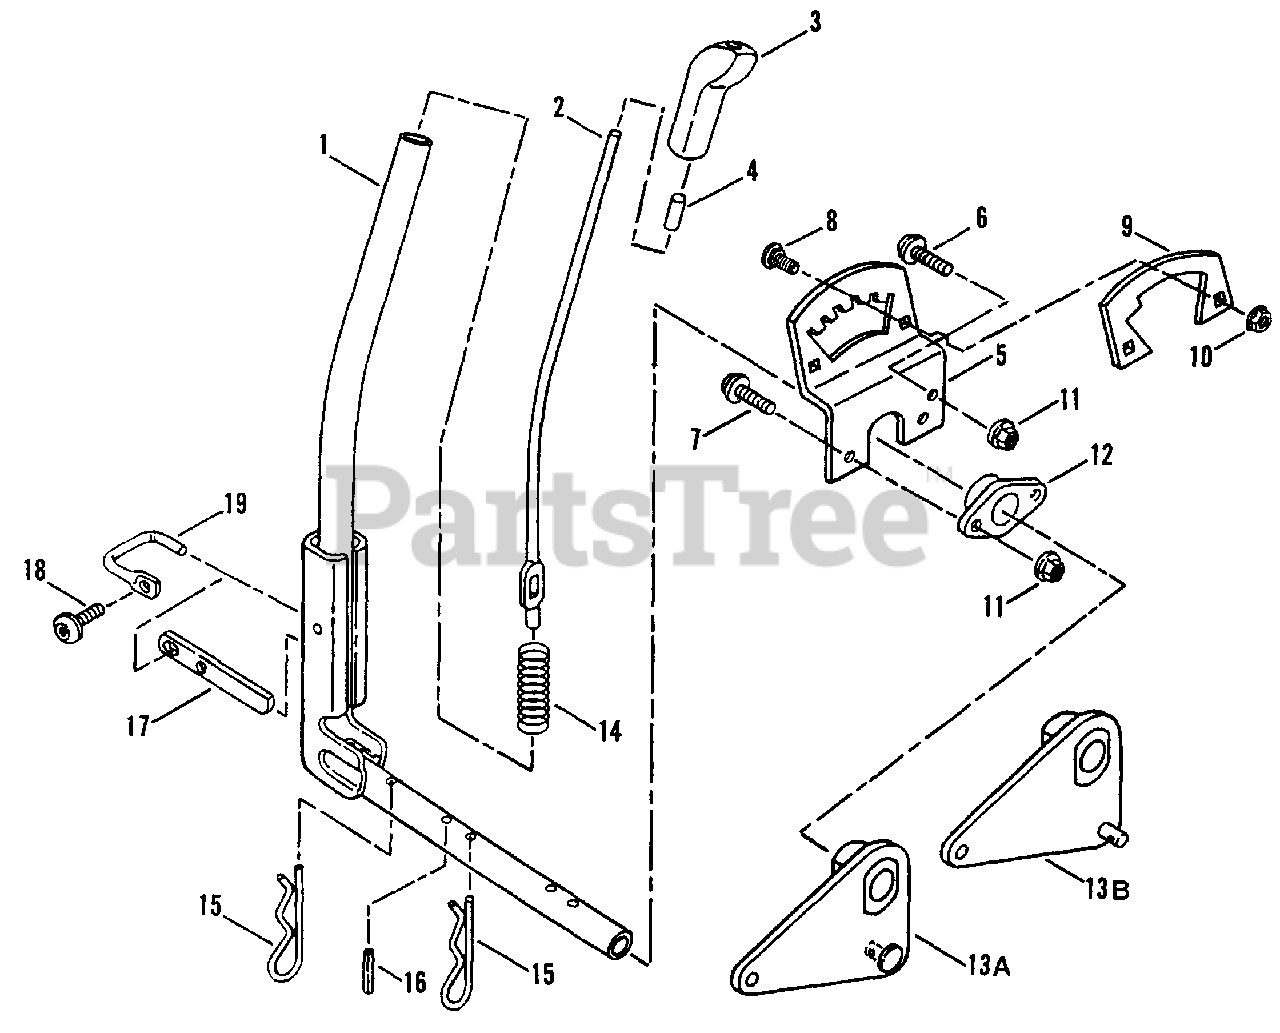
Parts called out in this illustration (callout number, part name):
1	LEVER, Implement Lift
2	ROD, Lift Lever
3	KNOB, Lift Lever
4	CAP, Lift Lever Rod
5	QUADRANT, Lift Lever
6	SCREW, 5/16-18 x 5/8" Truss Head (Torx)
7	SCREW, 5/16-18 x 7/8" Truss Head (Torx)
8	BOLT, 1/4-20 x 1/2" Short Neck Carriage
9	DETENT, Highcut Lockout
10	NUT, 1/4-20 Hex Flange Lock
11	NUT, 5/16-18 Hex Flange Lock
12	PIVOT, Lift Lever
13A	BELLCRANK, Lift Lever
13B	BELLCRANK, Lift Lever
15	PIN, Hair, 5/32 x 2 5/8"
16	PIN, Dowel, 1/4 x 1 1/8"
17	DETENT, Latch
18	SCREW, 1/4-20 x 5/8" Truss Head (Torx)
19	LATCH, Pivot
